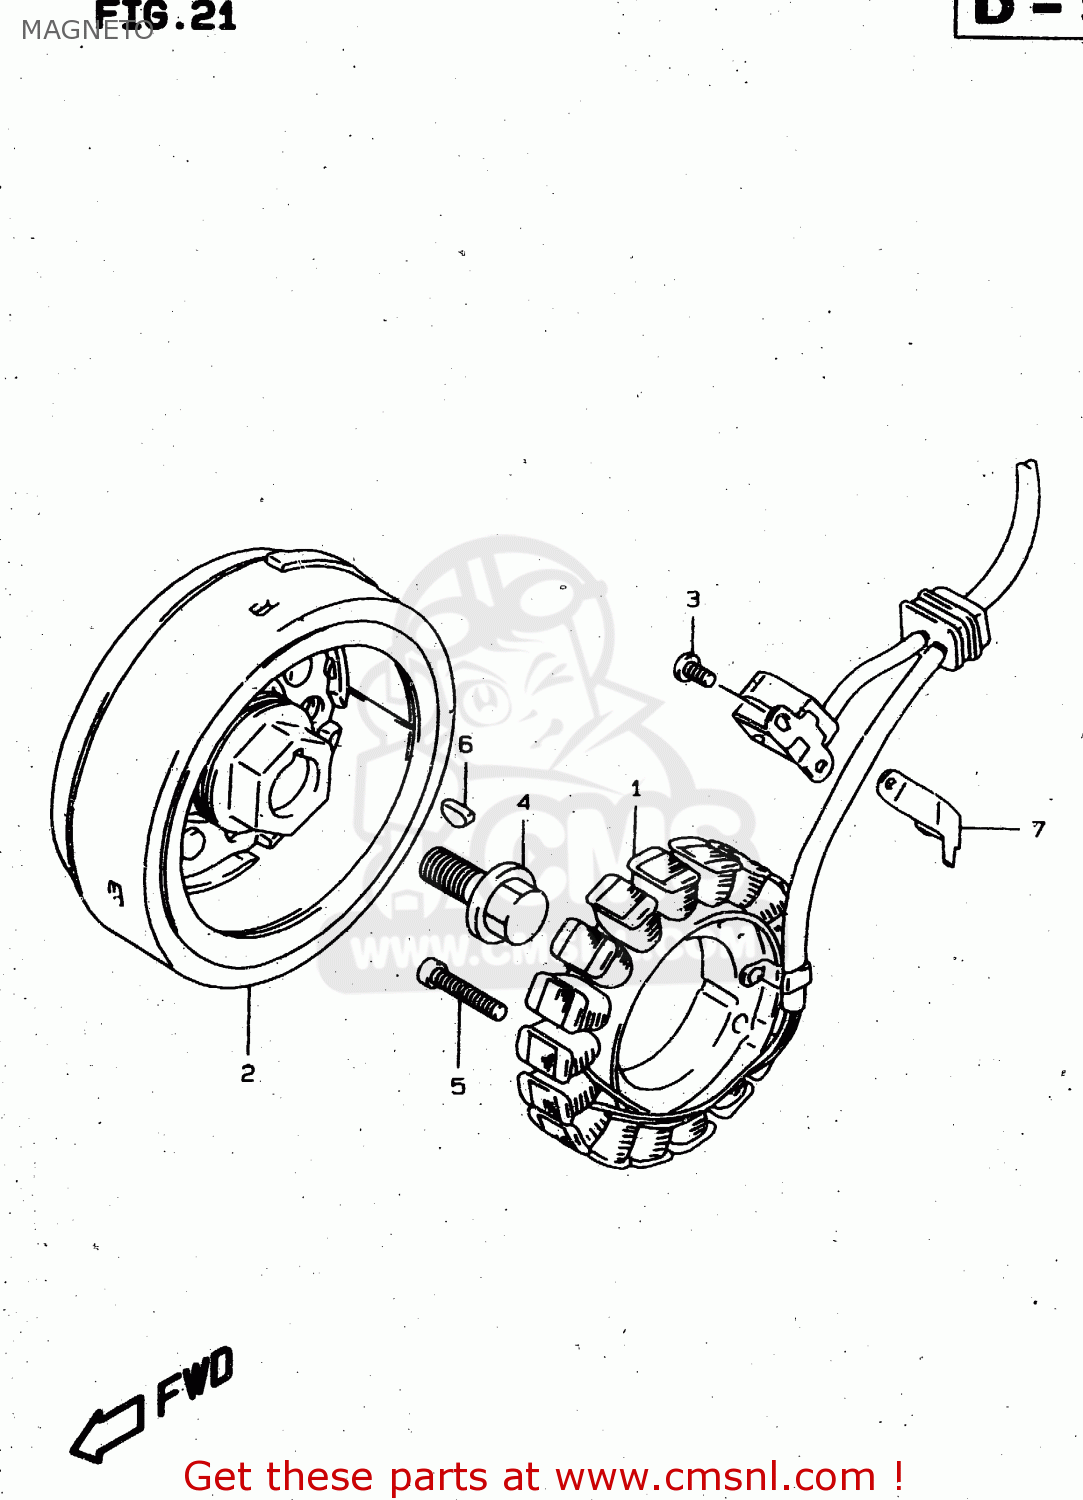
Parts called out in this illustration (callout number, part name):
1	STARTER ASSY
2	ROTOR ASSY
3	SCREW
4	BOLT(14X43)
5	BOLT
6	KEY
7	CLAMP,MAGNETO LEAD
